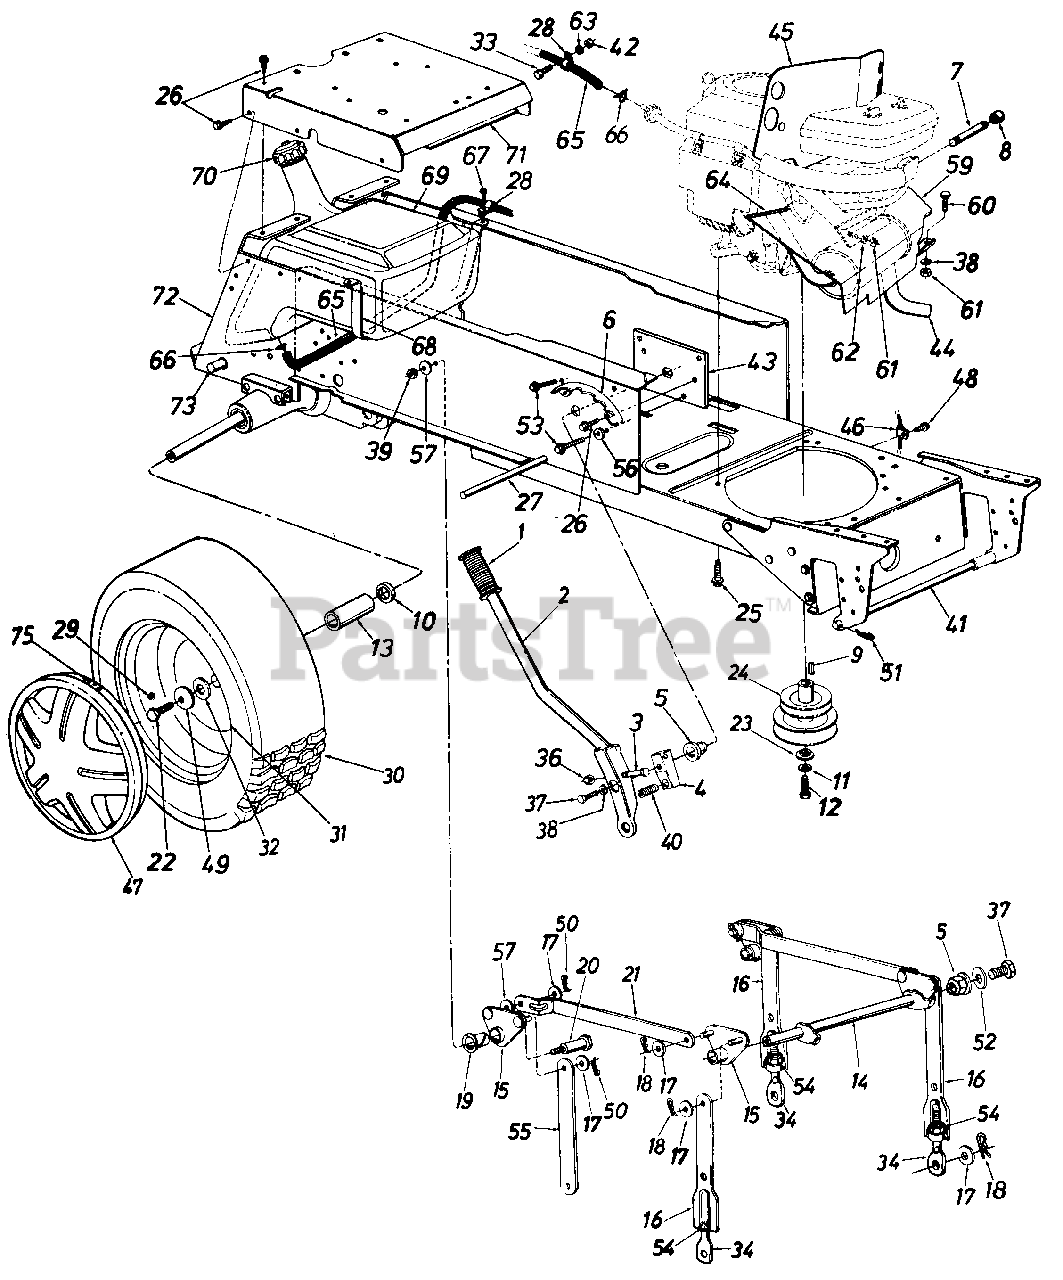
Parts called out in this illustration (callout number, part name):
1	Grip
2	Lift Handle Ass'y.
3	Hex Bolt 5/16-18 x 1.5" Lg.
4	Lift Shaft Drive
5	Plastic Hex Brg. 5/8" I.D.
8	Pipe Cap 3/8-18 Npt.
9	Sq. Key 1/4" x 1/4" x 1.50" Lg.
10	Fl-wash .76" I.D. x 1.49" O.D.
11	L-Wash. 7/16" I.D.
12	Hex Scr. 7/16-20 x 1.50" Lg.
13	Sleeve .75" I.D. x 1.0" O.D.
14	Lift Shaft Ass'y.
15	Lift Pivot Brkt. Ass'y.
17	Fl-Wash. 1/2" I.D. x 1.00" O.D. x .ogon
18	Hairpin Cotter
19	Nyliner 5/8" I.D. x .88" Lg.
20	Shld. Bolt 5/8 Dia. x .96" Lg. 3/8-16
23	Flat Wash. .44" l.D. x 1.25" O.D. x .17"
24	Two-Step Engine Pulley 5.56 & 3.5
25	Hex Wash. Hd. Scr. 3/8-16 x 1.25" Lg.
26	Hex Thd. Rolling Scr. 5/16-18 x.75" Lg.
27	Running Board Rod
29	Air Valve
32	Flat Washer .34 l.D.
33	Hex Bolt 1/4-20 x .62" Lg.
34	Eye Bolt Adj. Link 1/2-13 Thd.
36	Hex Cent. L-Nut 5/16-18 Thd.
37	Hex Bolt 5/16-24 x .62" Lg.
38	L-Wash. 5/16" l.D.
39	Hex Top L-Nut 3/8-16 Thd.
40	Compression Spring
41	Deck Connecting Rod
42	Hex Nut 1/4-20 Thd.
45	Heat Shield
46	Mounting Clamp
47	Hubcap
48	Hex Wash. Hd. TT-Tap Scr. 1/4-20 x .5" Lg
49	Bell-Wash. .39" l.D.
50	Cotter Pin .09 Dia. x 1.0" Lg.
51	Int. Cotter Pin
52	Flat Wash. ,34" l.D. x 1.12" O.D. x .125n
53	Hex Wash. Hd. AB-Tap Scr. 5/16-24 x .5" Lg.
54	Hex Nut 1/2-13 Thd.
56	Fl-Wash. ,344" l.D.
57	Bell-Wash. .4" l.D. x 1.13 O.D>
59	Front Heat Shield
60	Hex Bolt 5/16-18 x ,75" Lg.
61	Hex Nut 5/16-18 Thd.
62	L-Wash. 5/16" l.D.
63	L-Wash. 1/4" l.D.
64	Trim Strip 10" Lg.
65	Fuel Line 50" Lg.
67	Hex AB-Tap Scr. 1/4 x .62" Lg.
68	Fuel Tank Strap
69	Gas Tank
70	Gas Gauge
71	Seat Plate
75	Spring Clip
